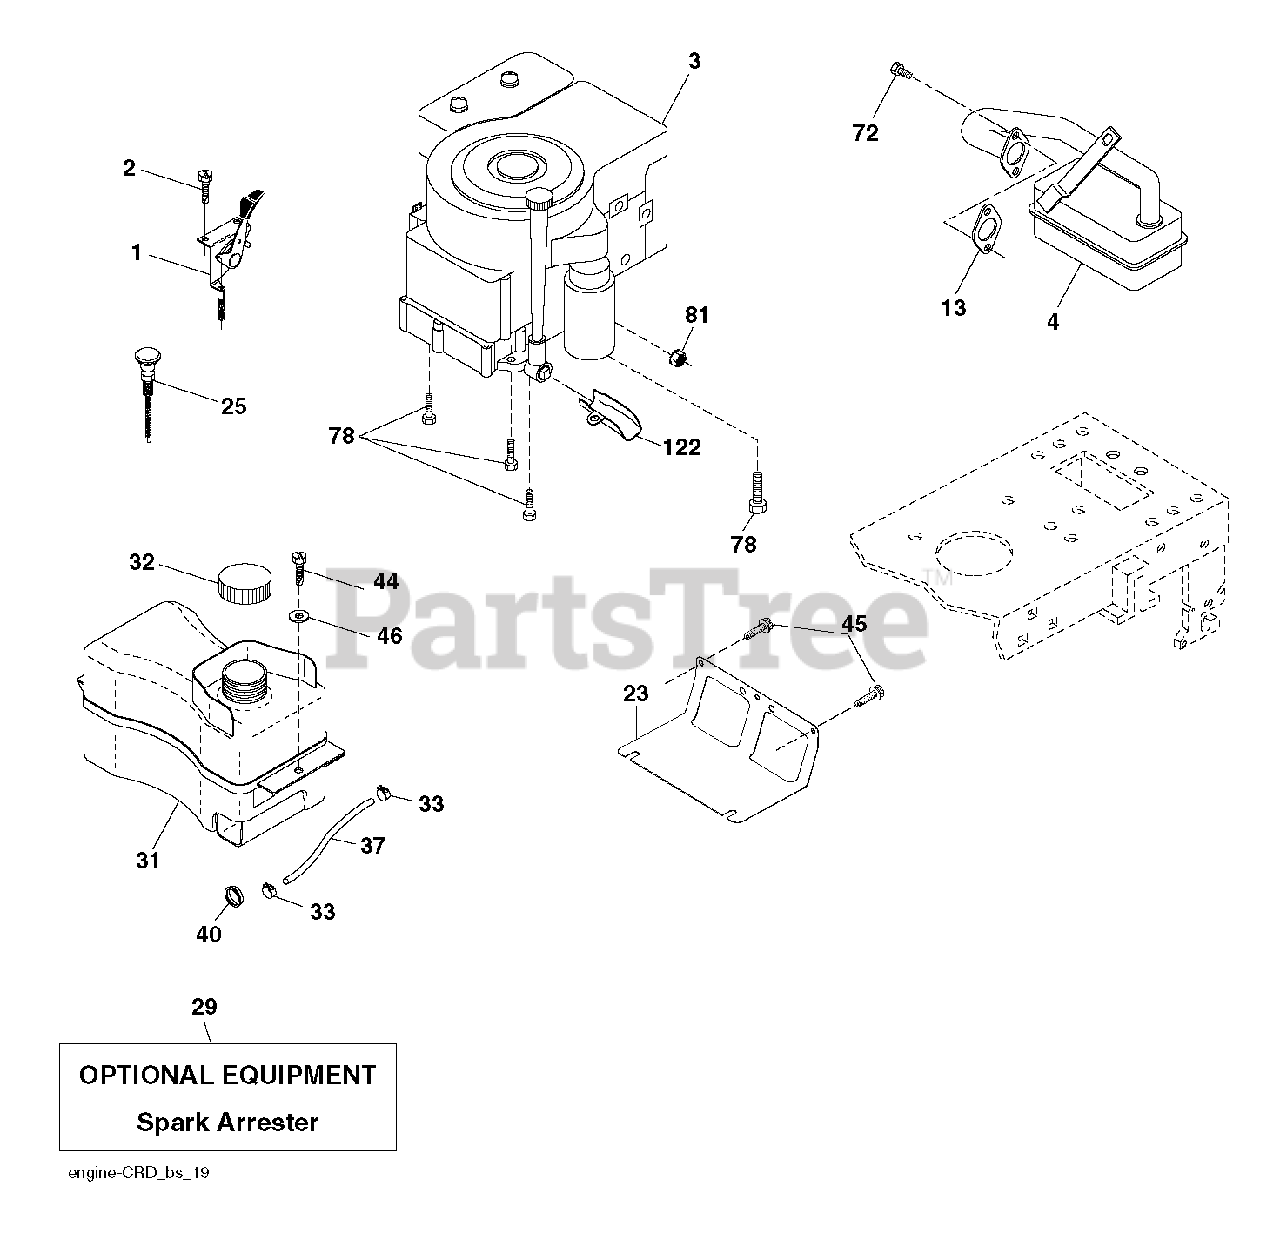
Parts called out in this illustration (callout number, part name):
1	CONTROL.THROTTLE/CHOKE.BLACK
2	SCREW
4	MUFFLER.B&S.MODEL.21.11HP.OHV
23	SHIELD.BROWNING.DBR.GUARD
25	KNOB.ERGO.EXTENDED.RED (1 2)
29	KIT.SPARK ARRESTOR(392390 B&S)
32	CAP ASM.FUEL.2.25"FR.
33	HOSE CLAMP
37	LINE.FUEL.20
40	GROMMET T
44	SCREW HEXWSHR 1/4-20X3/4
45	SCREW, 3/8-16X3/4
72	SCREW.SOCKET HD.5/16-1
78	SCREW.3/8-16
81	NUT
122	EXTENSION DRAIN OIL
